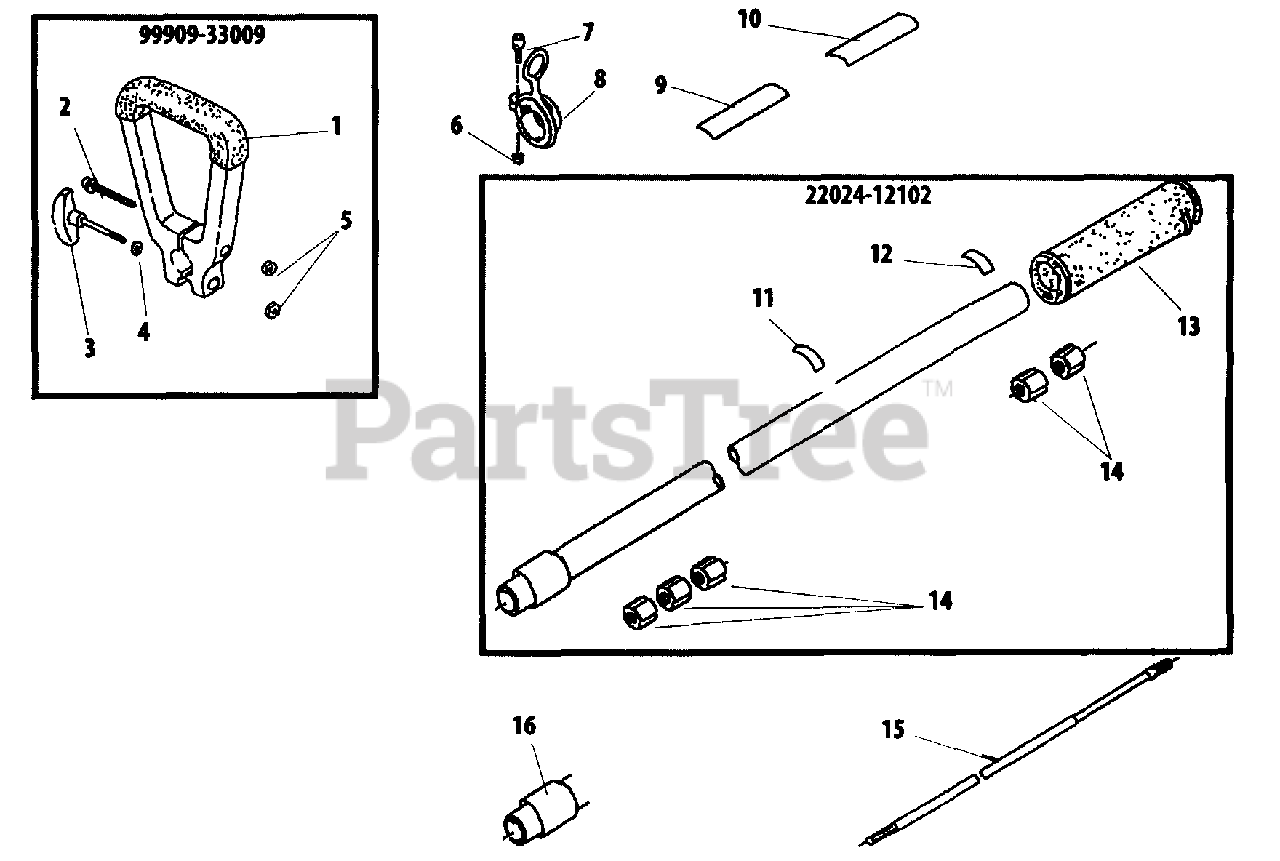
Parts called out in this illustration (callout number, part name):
1	HANDLE
2	SCREW 6
3	KNOB, SCREW
4	WASHER 6
5	NUT, HEX M6
6	NUT M5
7	BOLT M5×12
8	HANGER, SWIVEL
9	LABEL
10	LABEL, CAUTION
11	LABEL, HANDLE
12	LABEL - ALIGNMENT
13	GRIP
14	BUSHING
15	MAINSHAFT
16	TUBE PROTECTOR
